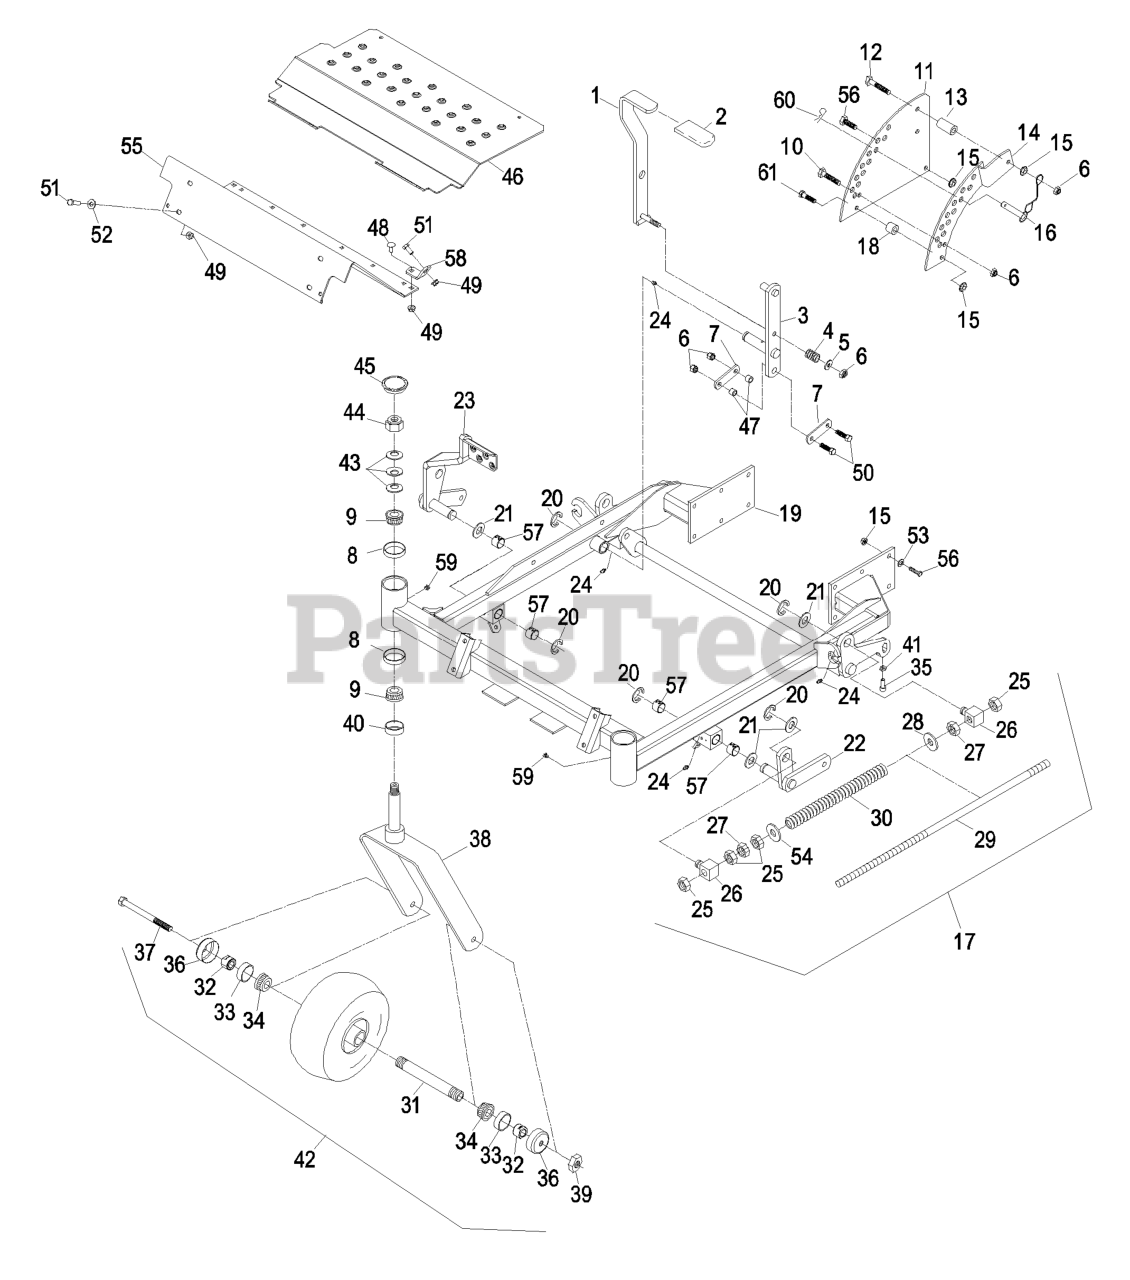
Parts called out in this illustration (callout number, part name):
1	ASM, LIFT LEVER / GRIP
2	GRIP-LEVER, LIFT
3	WLD, DECK LIFT ARM-LHP
4	SPRING-COMPRESSION
5	WASHER-FLAT
6	NUT-LOCK, NI
7	ARM-LIFT, DECK
8	CUP-BEARING
9	Cone-Bearing Tapered Roller
10	SCREW-HH
11	PLATE-LIFT, DECK
12	SCREW-HH
13	BUSHING-LEVER, LIFT
14	PLATE-LIFT, DECK W/DECAL
15	NUT-HHF, WHIZ
16	PIN-HITCH (W/LANYARD)
17	FRONT SPRING ASM
18	BUSHING-LEVER, LIFT
19	KIT, FRONT FRAME-LHP52
20	RING-RETAINING, EXT
21	WASHER-FLAT
22	WLD,SHAFT LH
23	WLD,FOOT DECK LIFT
24	FITTING-GREASE
25	NUT-HEX
26	SWIVEL-DECK MOUNT, REAR
27	NUT-JAM
29	ROD-LIFT, DECK
30	SPRING-COMPRESSION
32	SPACER-NUT
33	SEAL-CASTER
34	BEARING-CONE, TAPERED ROLLER
35	SCREW-HSH
36	GUARD-SEAL
37	SCREW-HH
39	NUT-HEX
40	SEAL-GREASE
41	NUT-JAM
42	ASM, WHEEL AND TIRE W/ AX
43	WASHER-BELLVILLE
44	NUT-LOCK, NI
45	CAP-GREASE
46	FLOORPAN,LIFTOUT
47	BUSHING
48	BOLT-CARR
50	SCREW-HH
51	SCREW-HH
52	WASHER-FLAT
53	WASHER-BELLEVILLE
54	WASHER-FLAT
55	FLOORPAN,FRONT LIFTOUT
56	SCREW-HH
57	BUSHING,SPRING
58	BRACKET-FLOORPAN
60	PIN-COTTER
61	SCREW-HH
